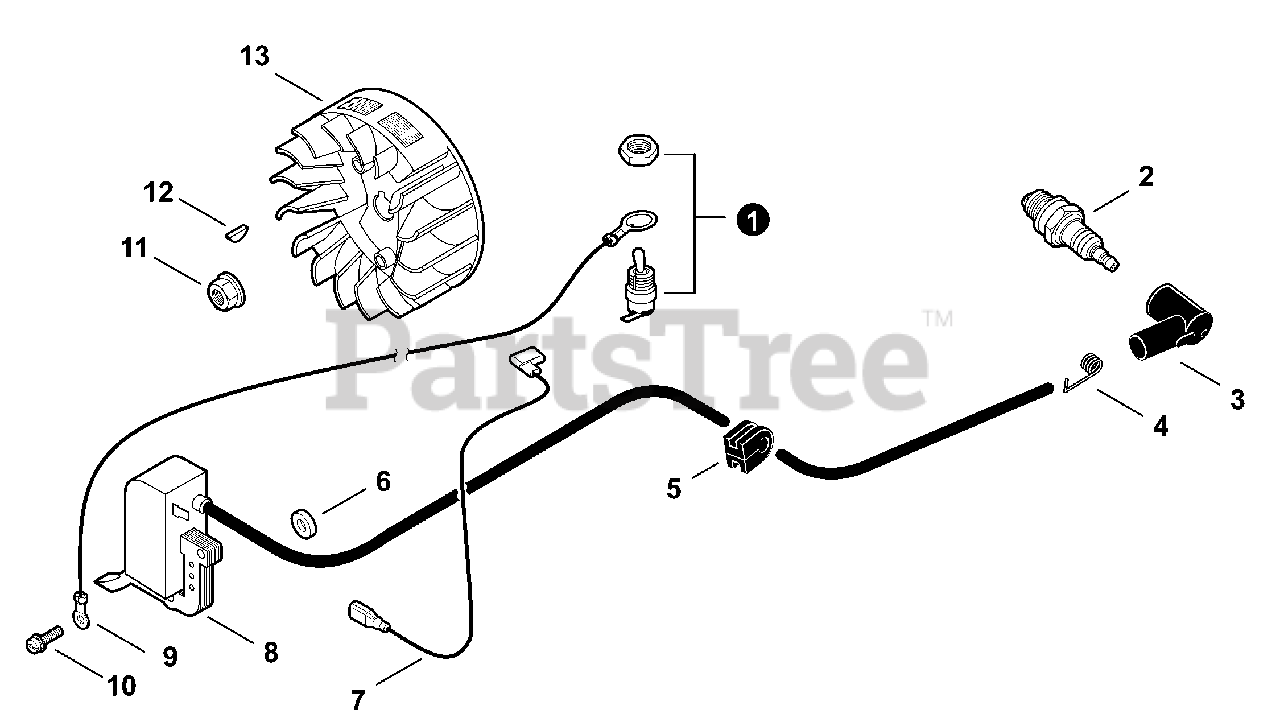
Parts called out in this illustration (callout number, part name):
1	SWITCH, ON-OFF
2	SPARK PLUG - BPM8Y
3	CAP, SPARK PLUG
4	TERMINAL, SPARK PLUG
6	WASHER 5.2×12×3
7	LEAD - IGNITION L= 95
8	COIL, IGNITION
9	LEAD - GROUND L= 100
10	SCREW 5×22
11	NUT, FLANGE M8
12	KEY, WOODRUFF
13	FLYWHEEL
